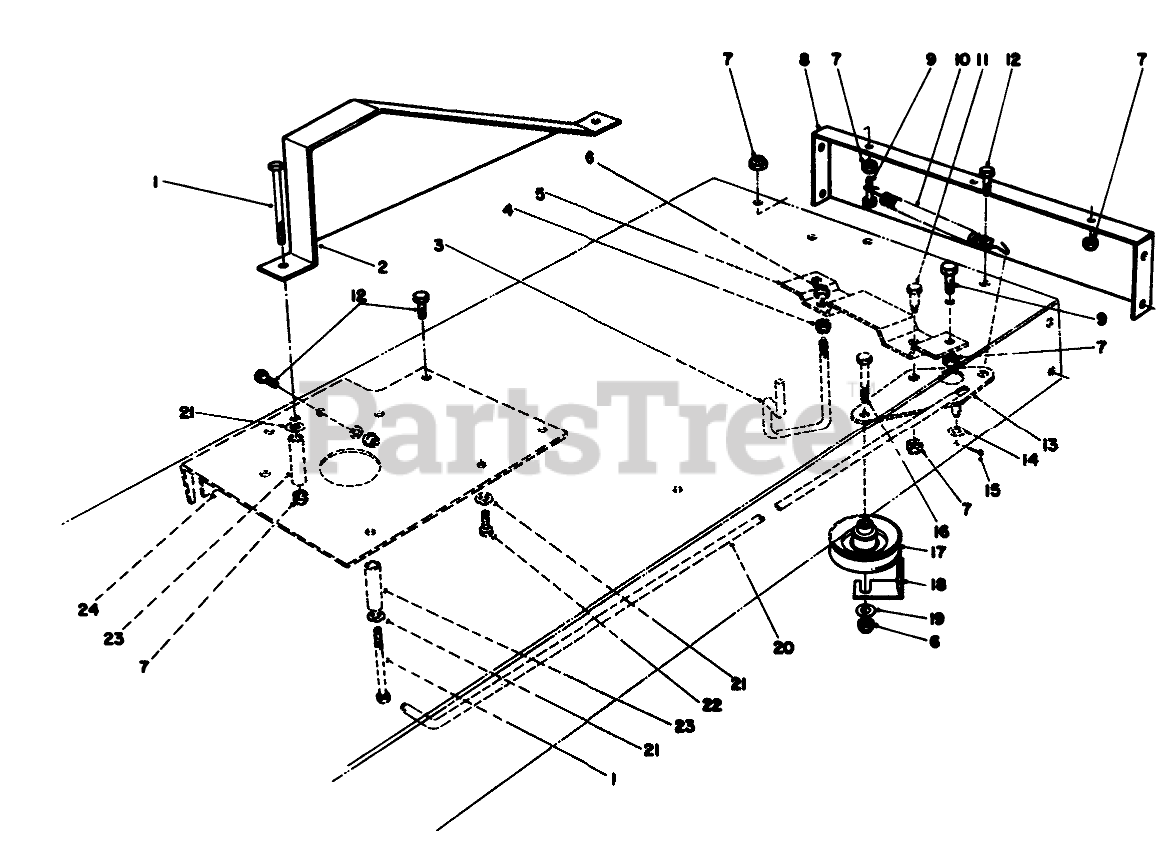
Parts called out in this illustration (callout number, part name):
1	SCREW-HH
2	CHAIN GUARD R
3	BELT GUIDE
4	NUT-LOCK, SIDE
5	TRACT SUPP BRKT B
6	NUT-LOCK, CONE
7	NUT-LOCK, NI
8	REAR FRAME R
9	SCREW-HH
10	TRACTION SPRING
11	BOLT-SHOULDER
12	SCREW-HH
13	TRACTION PIVOT BRKT
14	WASHER-FLAT
15	PIN-COTTER
16	SCREW-HH
17	PULLEY-IDLER
18	RETAINER-BELT
19	WASHER-FLAT
20	TRACTION ROD
21	WASHER-PLAIN
22	Screw-HH
23	OUTER TUBE SPACER
24	REINF PLATE R
